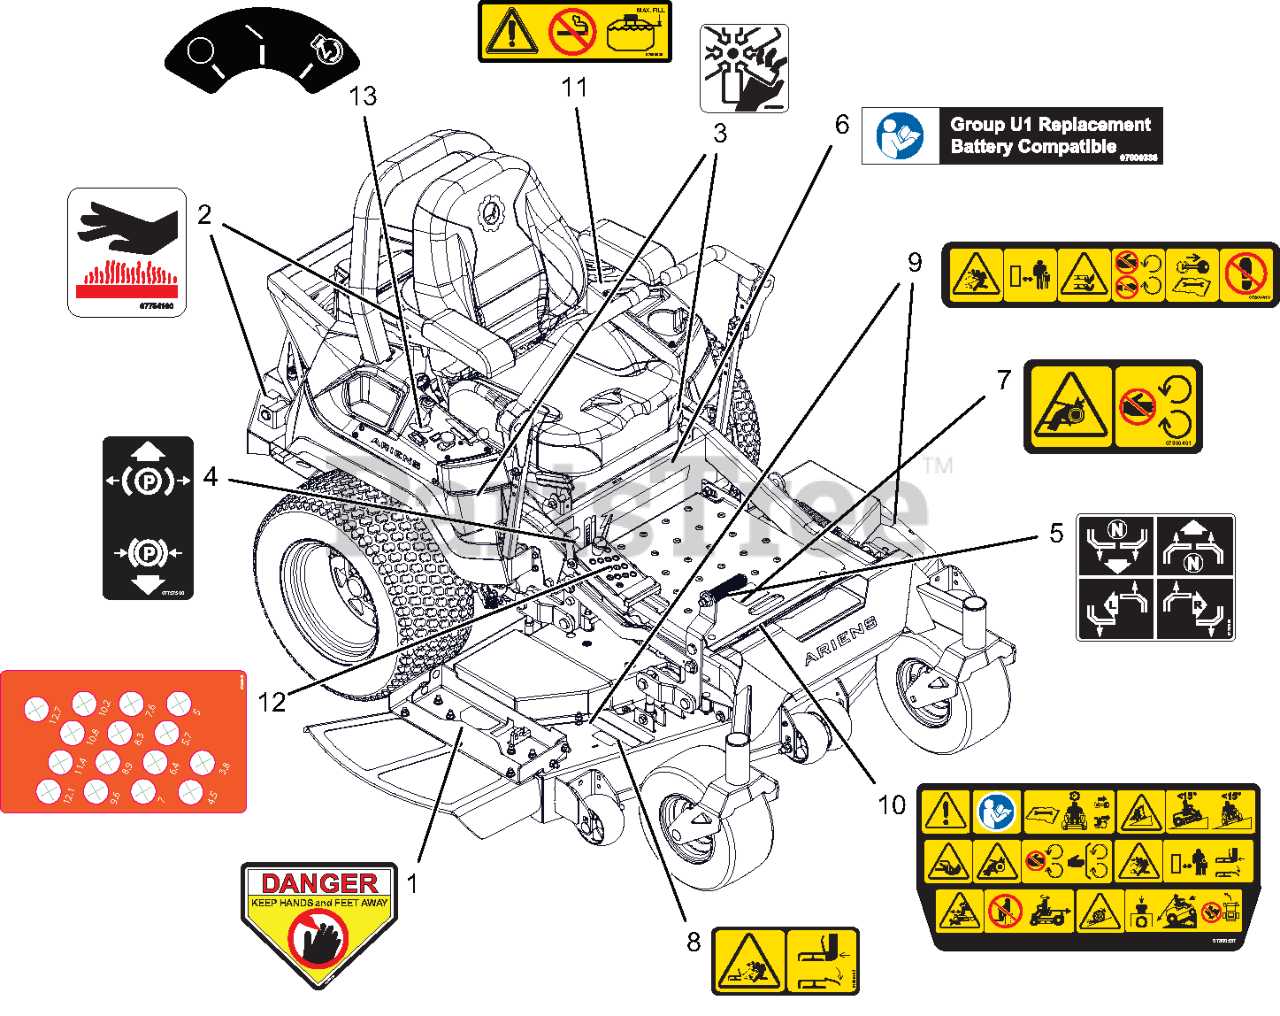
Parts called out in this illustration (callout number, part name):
1	DECAL, DANGER
2	DECAL, HOT SURFACE
3	DECAL, DANGER FAN
4	DECAL, PARKING BRAKE LEVER
5	DECAL, INSTRUCTIONAL-STEERING
6	DECAL, U1 BATTERY REPLACEMENT
7	DECAL, SAFETY - GUARDING
8	DECAL, SAFETY - DECK GUARDING
9	DECAL, DECK SAFETY
10	DECAL, MAIN SAFETY
11	DECAL, FUEL WARNING
12	DECAL, APEX HOC METRIC
13	DECAL, KEYSWITCH
